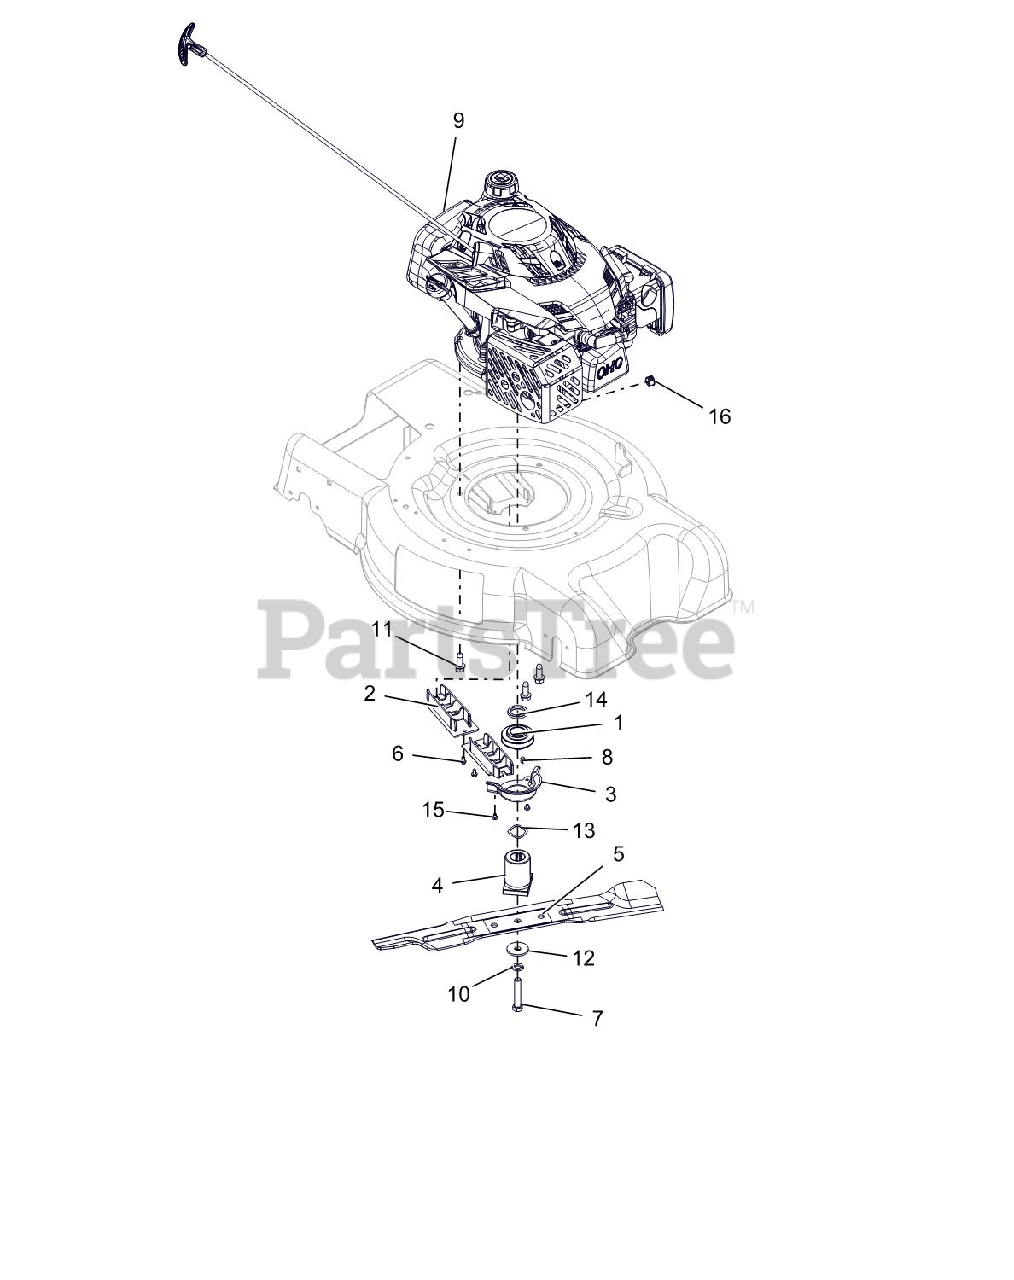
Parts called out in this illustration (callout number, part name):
1	PULLEY, GROUND DRIVE, LM
2	GUIDE, BELT INNER
3	GUIDE, BELT CRANK
4	ADAPTER, BLADE
5	BLADE, MOWER 21" HIGH LIFT
6	SCR-TAP 10-24X.375 PRE-COAT 80
7	@BLT-HEX .4375-20X2.25 GR8 YWZ
8	KEY-SQ .188X.188X.375
9	ENGINE, SUBARU 175CC VERT
10	@WSHR-LK .44X.109 REG YWZC
11	@SCR-TAP .38-16X1.00 HWH TR YZ
12	WSHR-FL-STL .4375X1.50X.125 YZ
13	WASHER - WAVE 1.09X1.37X.016
14	SPCR, 1.00 X 1.375 X .179
15	SCR-TAP 10-24X.25 CRSLPH TR YZ
16	PLUG, DOME-BLACK, .625 DIA
